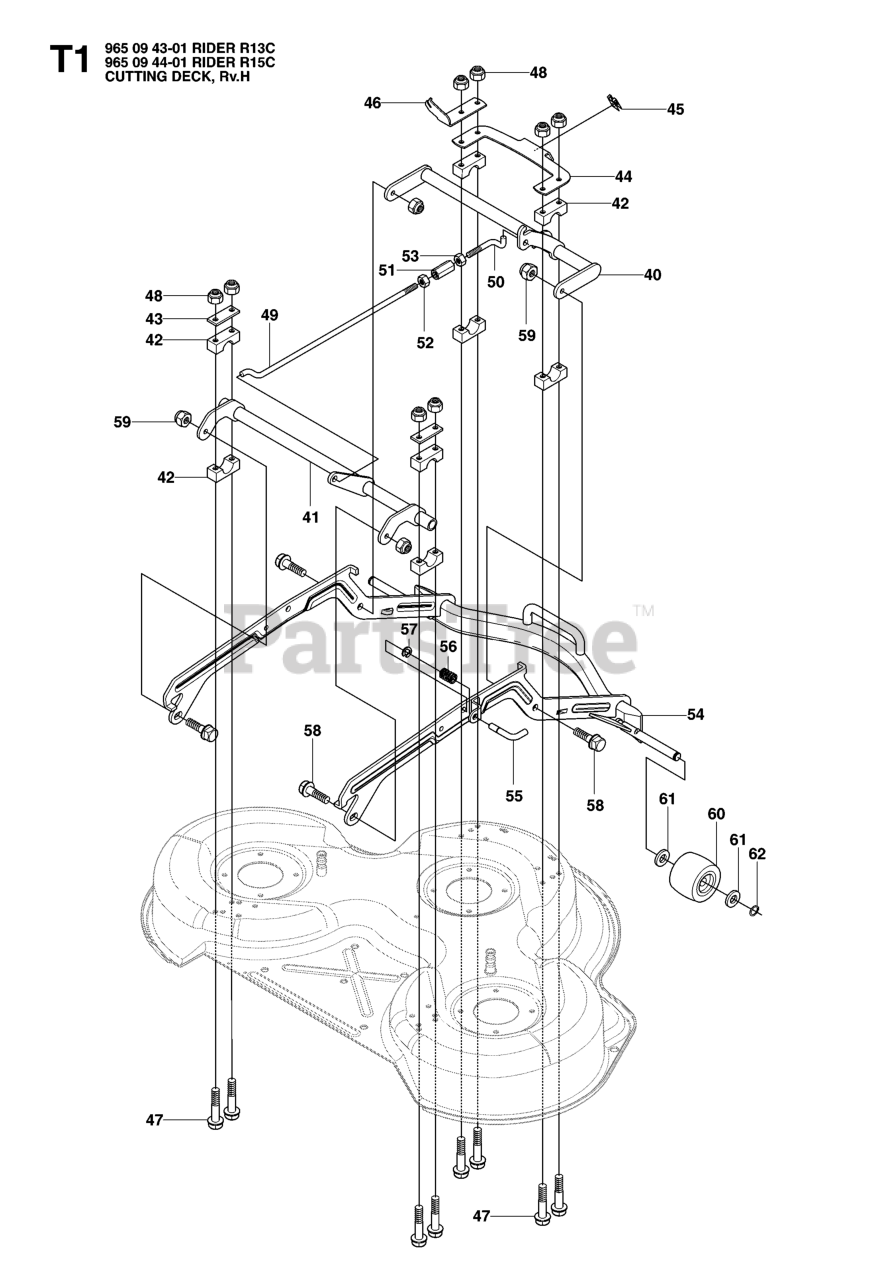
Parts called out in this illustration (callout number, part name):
46	BRACKET HANDLE
48	LOCKNUT M8
53	NUT
59	LOCKNUT M8
60	DECK ROLLER, FRONT
62	RETAINING RING SGA 15
